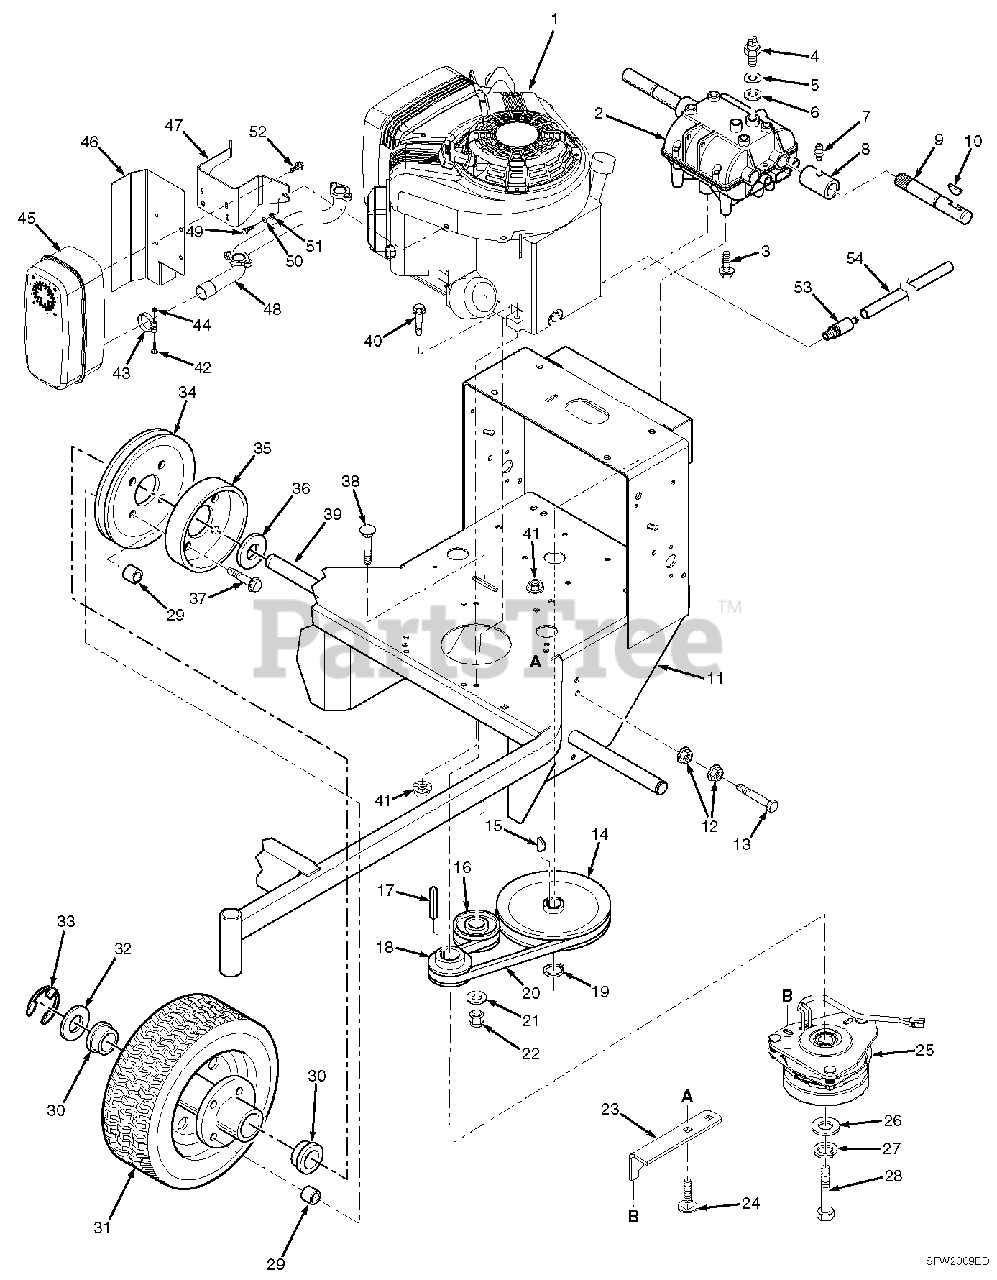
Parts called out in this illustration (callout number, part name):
1	Engine, Briggs & Stratton
2	Transmission, 4-Speed
3	Bolt, Serrated Flange 5/16-18 x 3/4"
4	Switch, Neutral Interlock
5	Fiber Washer, Thin
6	Fiber Washer, Thick
7	Grease Fitting, Straight 1/4-28
8	Coupler, Jackshaft
9	Jackshaft
10	Key, Hi-Pro #9
11	Frame Weldment w/Decals
12	Nut, Serrated Flange 3/8-16
13	Bolt, Hex Head 3/8-16 x 1"
14	Pulley, Transmission Input
15	Key, Woodruff #9
16	Pulley, Idler 3-1/2"
17	Key, 1/4 x 1/4 x 3/4"
18	Pulley, 2-3/4 OD x 1" Bore
19	Retaining Ring, .625 Ext.
20	Belt, Transmission
21	Flatwasher, 3/8-.391 x .935 x .105 HD
22	Nut, Elastic Stop 3/8-16
23	Bracket, Anti-Rotation
24	Bolt, Carriage 5/16-18 x 3/4"
25	Clutch, Ogura GT1A
26	Flatwasher, 7/16-.469 x 1-3/4 x .25
27	Lockwasher, 7/16" Spring
28	Bolt, Hex Head 7/16-20 x 2-3/4" w/ Patch
29	Spacer, Wheel Assembly
30	Bearing
31	Wheel Assembly
32	Flatwasher, 1-1.062 x 1-1/2 x .0478
33	Retaining Ring, 1" Ext. "E"
34	Pulley, Wheel
35	Brake Drum
36	Flatwasher, 1-1.063 x 1-1/2 x .105
37	Bolt, Hex Head 5/16-18 x 1-1/2" SF
38	Bolt, Carriage 3/8-16 x 2"
39	Wheel Axle
40	Bolt, Serrated Flange 5/16-18 x 1-1/2"
41	Nut, Serrated Flange 5/16-18
42	Bolt, Carriage 5/16-18 x 1-1/4"
43	Muffler Clamp
44	Nut, 5/16-18 UNC
45	Muffler, 16HP Briggs & Stratton
46	Heatshield, 16HP Briggs & Stratton
47	Mounting Bracket, Muffler 16HP Briggs & Stratton
48	Exhaust Manifold, 16HP Briggs & Stratton
49	Bolt, M6-1 x 16mm
50	Lockwasher, 1/4" Spring
51	Flatwasher, 1/4-.312 x .750 x .065
52	Capscrew, 1/4-20 x 3/4" Shakeproof
53	Oil Drain, SFW
54	Tubing, Oil Drain 1/2 x 14"
